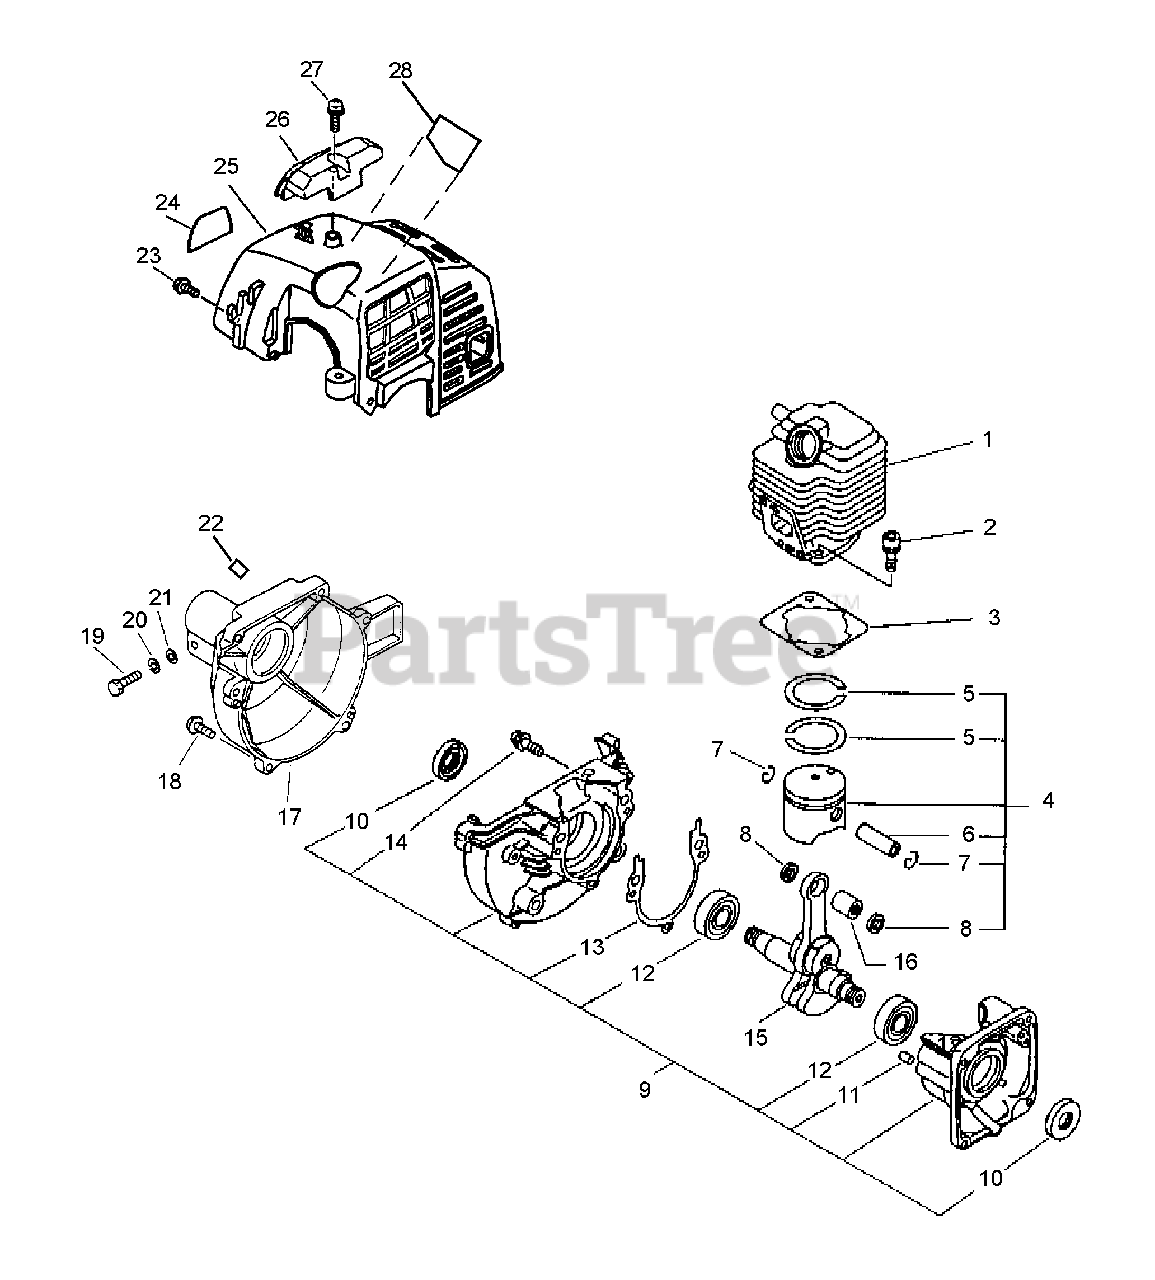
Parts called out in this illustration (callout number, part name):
1	CYLINDER
2	BOLT 5×22
3	GASKET, CYLINDER
4	PISTON KIT
5	RING, PISTON
6	PIN, PISTON 8
7	RING, SNAP
8	WASHER, THRUST
9	CRANKCASE ASSY
10	SEAL, OIL 12
11	PIN, LOCATING 4
12	BEARING, BALL - 6201 C3
13	GASKET, CRANKCASE
14	BOLT 5×28
15	CRANKSHAFT ASSY
16	BEARING, NEEDLE
17	COVER, FAN
18	BOLT 4×18
19	BOLT 5×28
20	WASHER, SPRING 5
21	WASHER, FLAT 5.5×10×0.8
22	NUT - 5 -- SQUARE
23	SCREW 4×12
24	LABEL, MODEL
25	COVER, ENGINE - ORANGE
26	GUARD, TOP - BLACK
27	SCREW 5×16
28	LABEL, CAUTION
